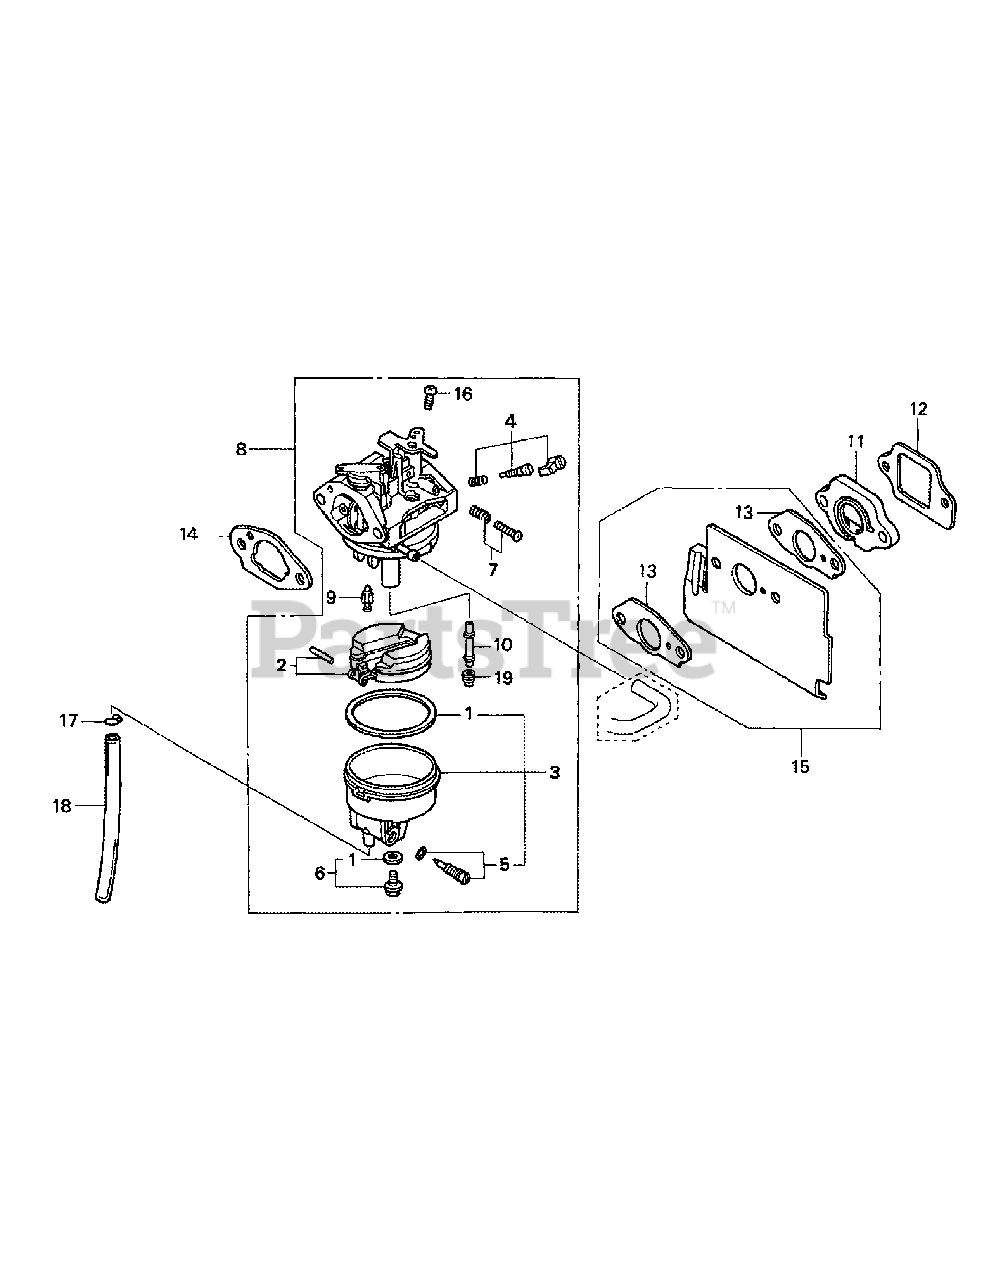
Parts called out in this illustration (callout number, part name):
1	Gasket Set
3	Float Chamber Set
5	Drain Screw Set
8	Carburetor Assembly, BB61K A
9	Float Valve
10	Main Nozzle
11	Carburetor Insulator
12	Insulator Gasket
13	Carburetor Gasket
14	Carburetor Gasket (Choke Side)
16	Pan Screw, 5 x 6
17	Tube Clip, B6.5
18	Vinyl Bulk Hose (4X7X8000, 4X7X150)
19	Main Jet, #62
19	Main Jet, #65
19	Main Jet, #68
